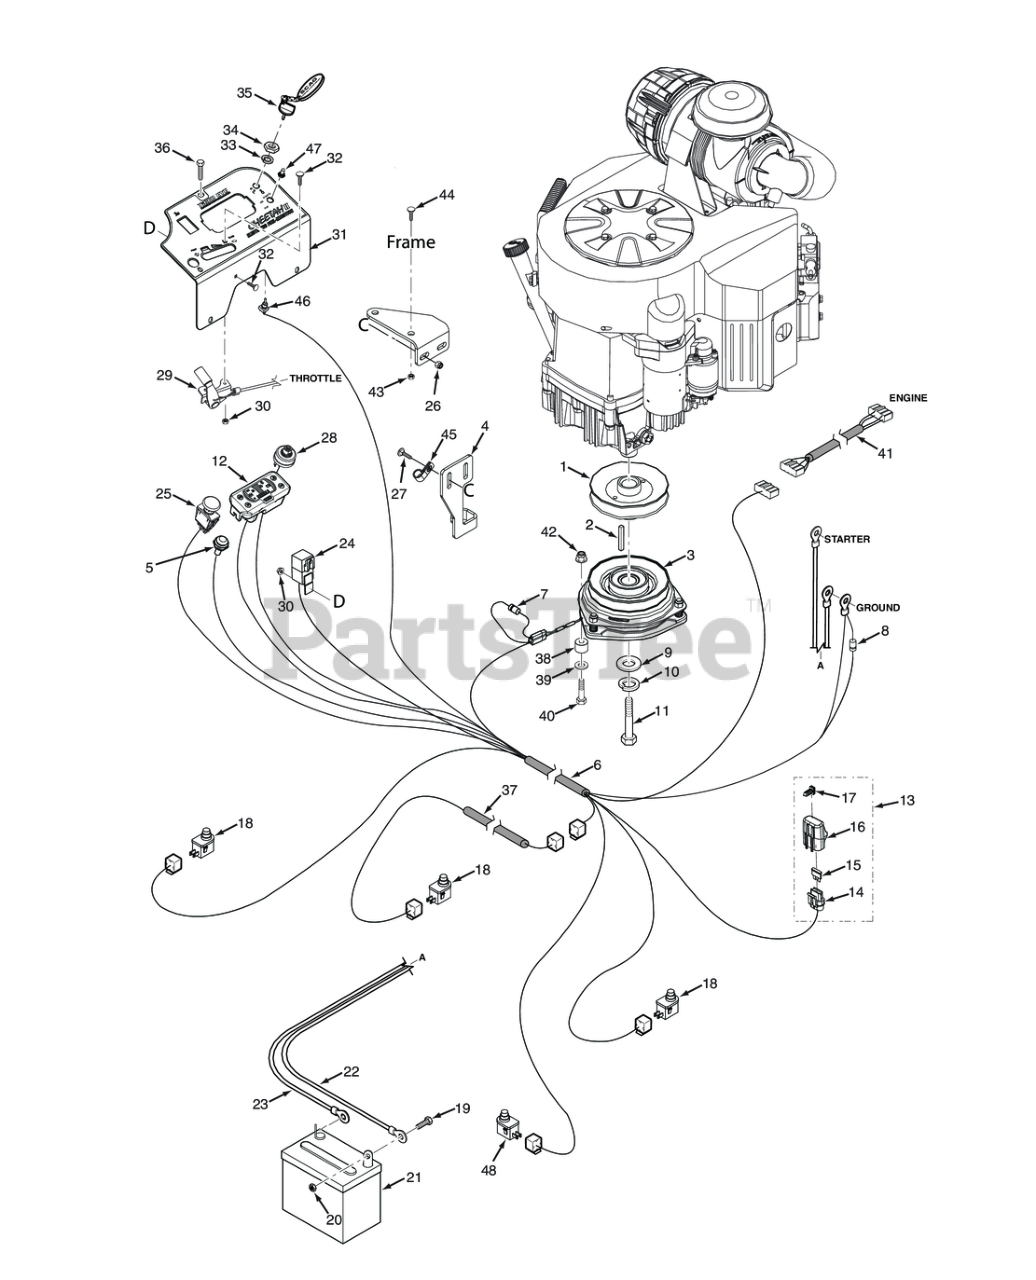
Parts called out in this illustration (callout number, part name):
1	Pulley, 5.80" Dia. - 1.125 Bore
2	Key, 1/4 x 1/4 x 3-1/4�
3	Electric Clutch w/Tag - GT-5 (ECV860, ECV940)
4	Bracket, Anti-Rotation
5	Indicator Light, Glow Plugs (Includes Mounting Hardware)
6	Wire Harness, SCZII-EFI
6	Wire Harness, SCZII-FX-EFI
7	Diode, 600V 6 Amp
8	Decal, Forward Speed Selector
9	Flatwasher, 7/16-.469 x 1.75 x .25 (48, 52)
10	Lockwasher, 7/16� Spring
11	Bolt, Hex Head 7/16-20 x 2-1/4" w/Patch (Kawasaki)
12	Tiger Eye, Cluster Gauge
13	Single Fuse Assy., Excluding Fuse
14	Fuse Holder Assembly
15	FUSE, 20 AMP BLADE TYPE AUTOMOTIVE
16	Cover, Sealed Single
17	Clip, Fuse Holder
18	Switch, Interlock, Normally Open
19	Bolt, Hex Head 1/4-20 x .5" Battery, (Not Available Through Scag)
20	Nut, 1/4 - 20 Hex
21	Battery
22	Battery Cable, 18" Black (Kohler)
23	Battery Cable, 25" Red
24	Relay, 12V 40 AMP Standard
25	Switch, PTO - 10 Amp
26	Nut, Flange Head Elastic Stop 5/16-18
27	Bolt, Carriage 5/16-18x1" (large frame units only)
28	KEY SWITCH(INCLUDES MOUNTING HARDWARE)
29	Control Cable (Kawasaki FX921 Throttle & Choke Cable)
30	Nut, Elastic Stop #10-24
31	Instrument Panel w/Decal
32	Bolt, Carriage #10-24 x 1/2"
33	LOCK WASHER, 5/8" INTERNAL TOOTH
34	Nut, 5/8-32 Special
35	Key, Assembly w/Fob
36	CAP SCREW, 1/4-20 X 1/2" SERRATED FLANGE HEX
37	Wire Harness, Operator Platform -SCZ
38	Bushing, UHMW
39	Flatwasher, 5/16-.375 x .875 x .083 (35BV & 37BV-EFI)
40	Bolt, Hex Head 5/16-18 x 1-1/2" (Right Front Engine Mounting, Briggs and Kohler Only)
41	Wire Harness Adapter, Briggs & Stratton 37 BV-EFI
42	HEX NUT, ELASTIC STOP LOCK, 5/16-18
43	NUT, 3/8-16 SERRATED FLANGE HEX HEAD
44	Carriage Bolt, 3/8-16 x 1.0"
45	Clamp, Cable 1/2" I.D.
46	SWITCH, ON / OFF
47	BOOT, SWITCH
48	Switch, N/C
